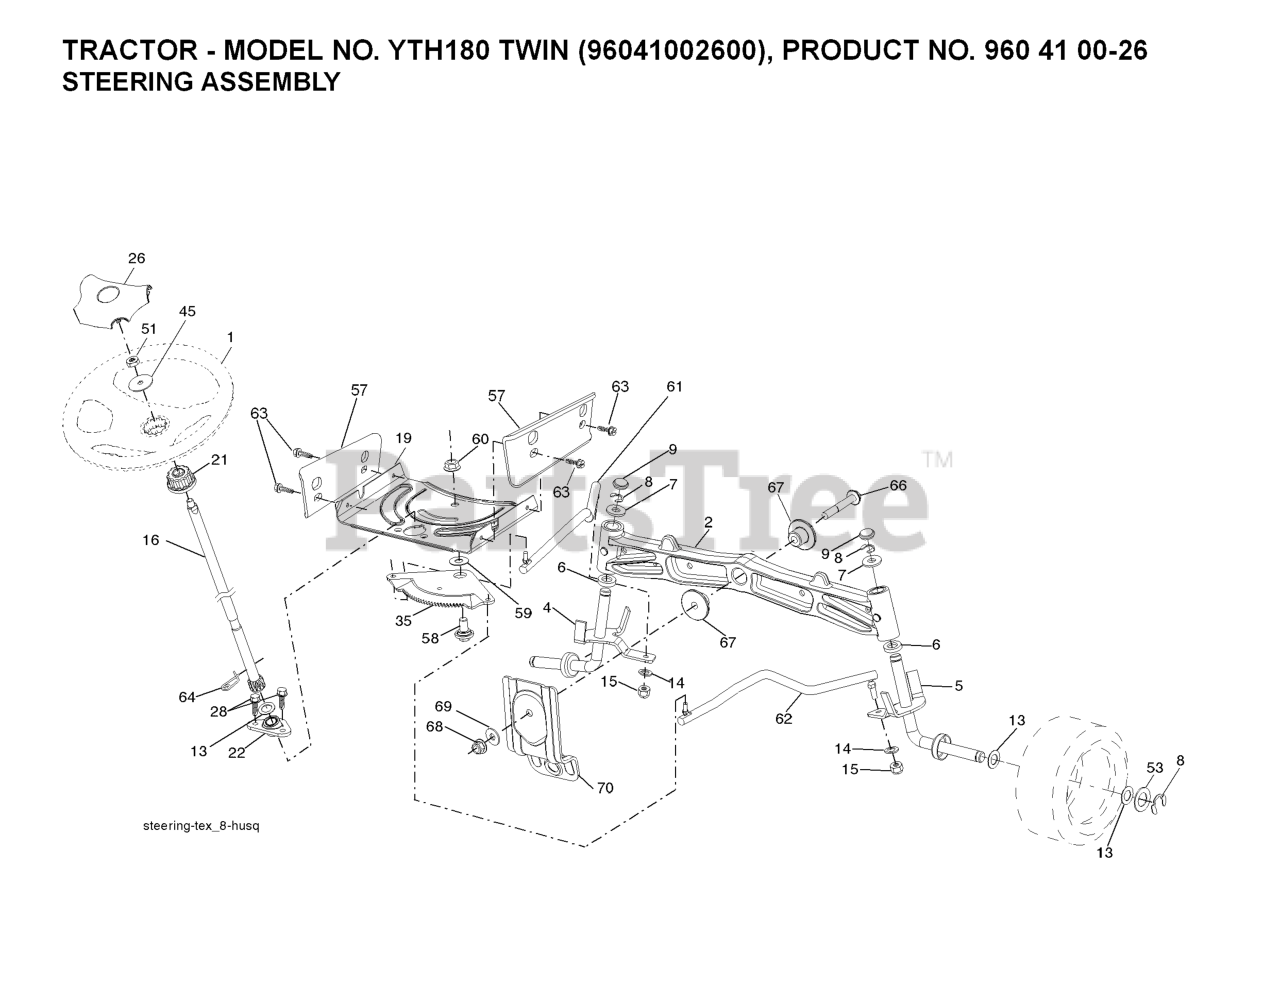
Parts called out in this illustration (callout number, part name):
1	STEERING WHEEL
2	AXLE.CAST.IRON
4	SPINDLE.WELDED.LH.15"TEX
5	SPINDLE.WELDED.RH.15"T
6	THRUST WASHER
9	CAP.SPINDLE.BLACK
14	WASHER, LOCK 3/8
15	NUT CROWNLOCK 3/8-24
16	SHAFT.STEER.STEALTH.DD
19	PLATE.STEER.DDL.NLT/NG
21	ADAPTER, WHEEL STNG..
22	BUSHING.ASM.STEERING.A
26	INSERT.CAP.STRG.WH.GRAY
28	SCREW, 3/8-16X3/4
35	GEAR.SECTOR.PLATE.DDL.
45	WASHER 9/16"ID, 2 3/8"OD
51	NUT.HEX.1/2-20
53	WASHER.HARDENED
57	BRACKET.UPSTOP.TEX
58	BOLT.SHOULDER.SECTOR.P
59	WASHER.THURST.SECTOR.S
60	NUT FLANGE LOCK 5/8-11
61	DRAGLINK.LH.BALLSTUD.D
62	DRAGLINK.RH.BALLSTUD.D
63	SCREW
64	RETAINER.CLIP.SPRING.S
66	BOLT HEX FGHD 7/16-14 X 3 SERR
67	BUSHING.PM.FRONT AXLE
68	NUT.LOCK.FLANGE.7/16
69	WASHER.1.5X.505X.118
70	BRKT.DECK.SUSPENSION.F
